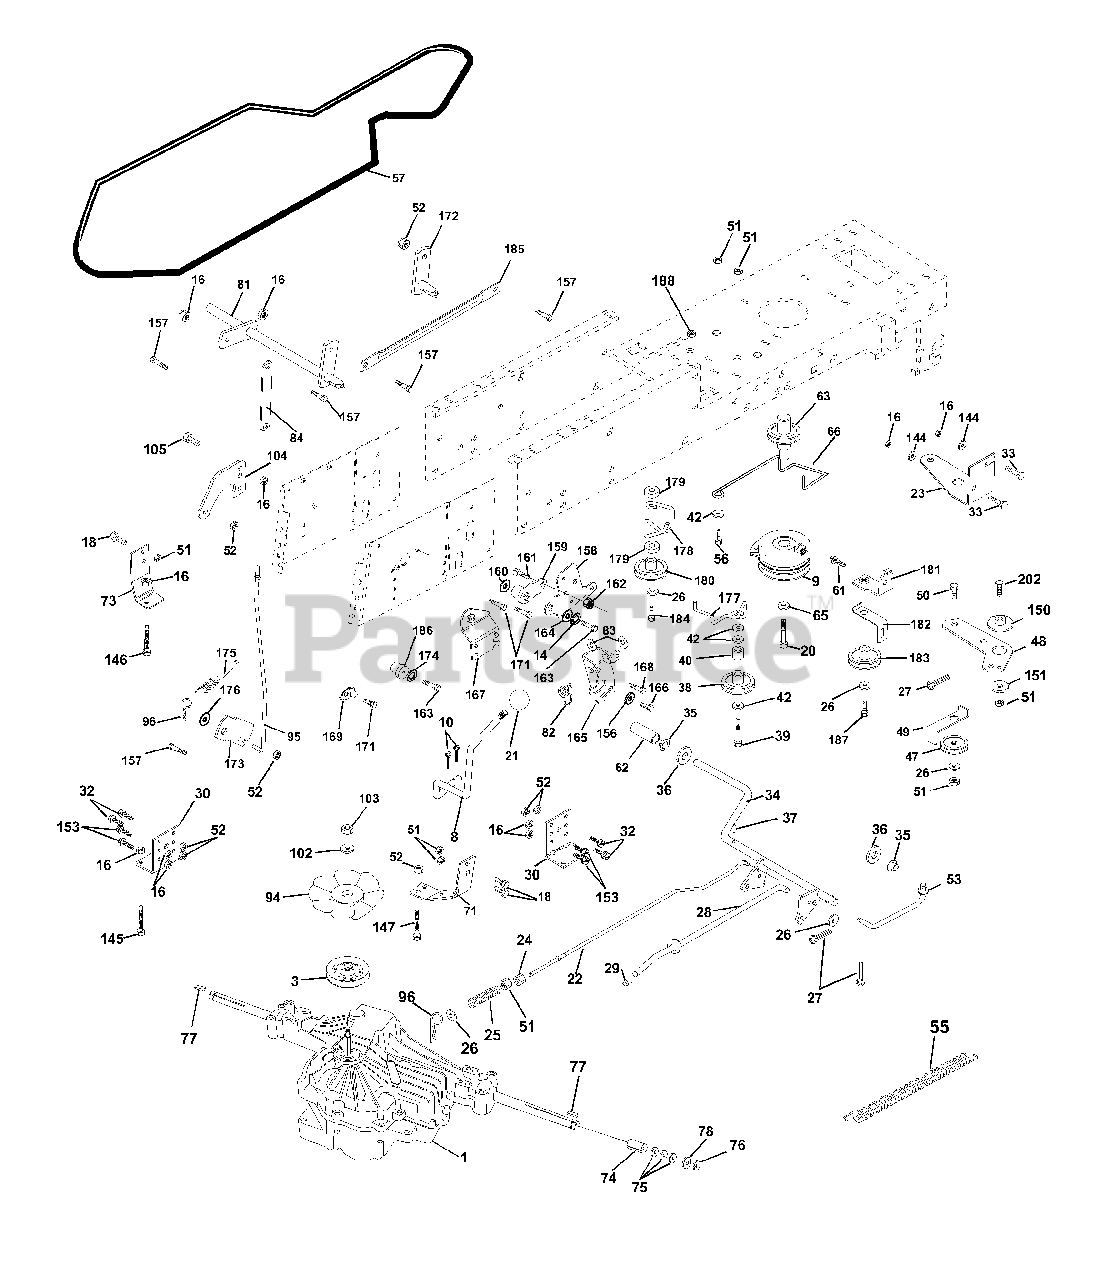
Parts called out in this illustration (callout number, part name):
1	Transaxle
3	Pulley, Transaxle
8	Rod Shift Fender Adjust
9	Clutch Elect Evx 80lb
10	Pin Cotter 1/8 x 1 CAD
14	Washer Lock Hvy Helical
18	Bolt Hex 3/8-16 Unc x 1 Gr. 5
20	Bolt, Hex 7/16-20 x 4-1/4
21	Knob, Duckhead 1/4-13 Unc Blk
22	Rod, Brake Hydro
23	Bracket Asm Anti-Rot EVX 2000
24	Nut Hex Jam 3/8-16
25	Spring, Brake Rod
26	Washer 13/32 x 13/16 x 16 Ga.
27	Pin Cotter 1/8 x 3/4 CAD.
28	Rod, Parking Brake
29	Cap, Parking Brake
30	Bracket, Transaxle
33	Bolt Rdhd Sqnk 5/16-18 unc x 3/4
34	Shaft, Foot Pedal
35	Bearing, Nylon
36	Washer 21/32 x 1 x 16 Ga
37	Pin, Roll
38	Pulley, Flat
39	Bolt Rdhd 3/8-16 Unc x 2-3/4 Gr. 5
40	Spacer, Split
42	Washer 13/32 x 13/16 x 12 Gauge
47	Pulley, Idler, V-Groove
48	Bellcrank Assembly
49	Retainer, Belt
50	Bolt Carr Sh 3/8-16 x 1-1/2 Gr. 5
51	Nut Crownlock 3/8-16 UNC
52	Nut Crownlock 5/16-18 UNC
53	Link, Clutch
55	Spring, Return, Clutch
56	Bolt Fin Hex 3/8-16 UNC x 1-1/4
57	V-Belt, Ground Drive
61	Screw 3/8-16 x 3/4
62	Cover, Pedal
63	Pulley, Engine
65	Washer
66	Keeper Belt Engine
71	Strap Torque Lh Hydro
73	Strap Torque Rh Hydro
74	Spacer, Split
75	Washer 25/32 x 1-1/4 x 16 Gauge
77	Key, Square
78	Washer 25/32 x 1-5/8 x 16 Gauge
81	Shaft Asm. Cross
82	Spring Torsion
83	Washer 17/32 x 3/4 x 16 Ga.
84	Link Transaxle
94	Fan, Hydro 7"
95	Rod Bypass CRD
96	Retainer Spring 1" Zinc/Cad
102	Washer Beliville .501D x 1.50D
103	Nut, Hex, Jam Toplock 1/2-20 UNF
104	Arm, Control Hydro
105	Screw Cap Hex 5/16 x 18 x 1
144	Washer 11/32 x 5/8 x 16 Ga.
145	Bolt Hex Flghd 5/16-18 Gr.5
146	Bolt Hex Flghd 5/16-18 x 2-1/4
147	Bolt Hex Flghd 5/16-18 x 1-1/2
150	Bushing Bellcrank
151	Washer 13/32 x 2 x 10 Ga.
153	Bolt Hex Hd 5/16-18 UNC x 1
156	Washer Srrted 5/16ID x 1.125
157	Bolt Shoulder 5/16-18 Unc - 2A
158	Bracket Shift Mount
159	Hub Tapered Flange Shift Lt
160	Washer 29/32 x 1-1/4 x 16 Ga
161	Bolt Rdhd Sqnk 1/4-20 x 3/4 Gr. 5
162	Nut Crownlock 1/4-20 Unc
163	Bolt Hex Fin 1/4-20 Unc x 1 Gr 5
164	Washer 5/8 x .281 x 10 Ga
165	Bracket Pivot Lever
166	Screw 5/16-18 x 5/8
167	Bracket Support Shift CRD
168	Bolt Shoulder 5/16-18 x .561
169	Plate Fastening Cross Shf. Stlt/CRD
172	Shaft Asm Shifter Frt CRD
173	Bracket Hydro Bypass CRD
174	Washer Lock 1/4
175	Spring Bypass CRD
176	Washer 7/32 x 1/2 x 16 Ga
177	Keeper Flat Idler
178	Keeper Belt Idler
179	Washer Sintered
180	Pulley Flat Idler
181	Bracket Idler Ground Drive CRD
182	Keeper Belt 2.5"OD V-Idler CRD
183	Pulley V-Idler 2.50"OD CRD
184	Scr Hexwsh Thdrol 3/8-16 x 2-3/4
185	Link shift CRD Hydro 0650
186	Hub Tapered Round CRD
187	Screw Thdrol 3/8-16 x 1-1/4
188	Bushing Snap Split Blk
190	Screw Thdrol 3/8-16 x 1/2 Tytt
191	Bolt Shoulder 5/16-18 Unc - 2A
192	Nut Crown Lock 5/16-18
193	Bolt Hex Hd 5/16-18
194	Nut Crown Lock 3/8-16 Unc
